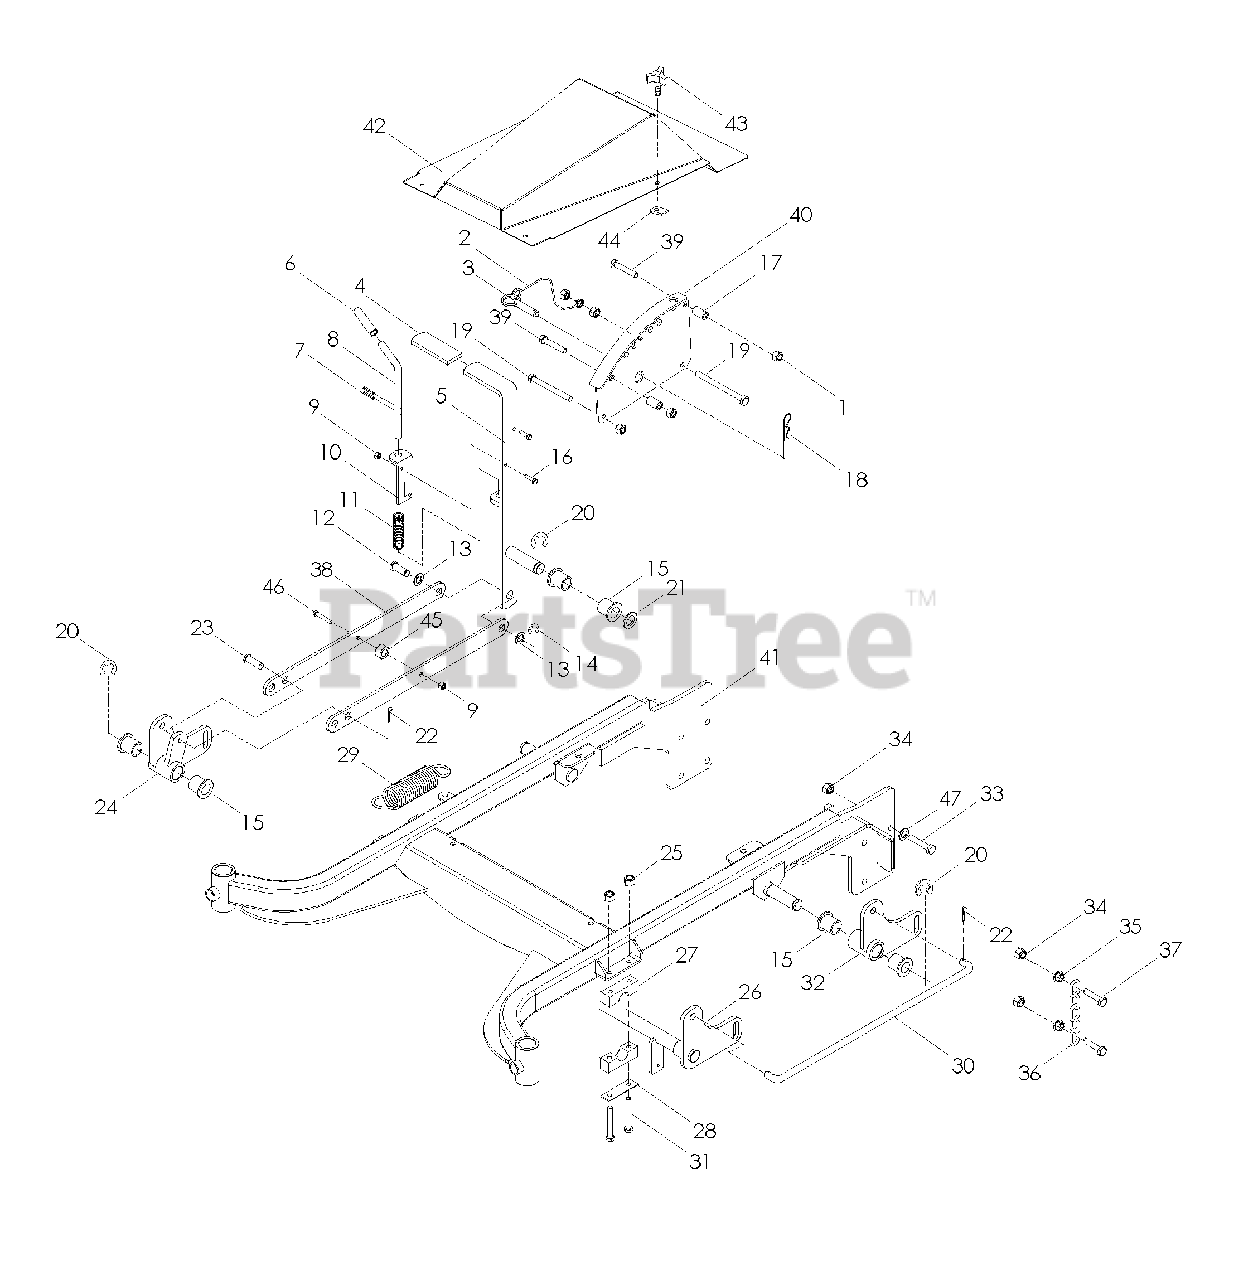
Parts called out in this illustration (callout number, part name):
1	NUT 3/8-16 HEX CNTRLK
4	GRIP, LIFT LEVER
5	LEVER, LIFT
7	PIN, GROOVED
8	PIN, LIFT LEVER
9	NUT 1/4-20 CNTRLK
10	MOUNT, PIN
12	CLEVIS PIN
13	BUSHING 5/8 MACHINERY
14	E-RING 5/8
15	BUSHING 7/8 FLANGED
16	HCS 1/4-20 x 3/4
18	HAIRPIN 2 1/2
19	HCS 3/8-16 x 4 1/2
20	E-RING 7/8
21	BUSHING, MACHINE
22	PIN, COTTER 5/32 x 1 1/4
23	PIN, CLEVIS 3/8 x 1 1/8
24	BELLCRANK, RIGHT
25	NUT 5/16-18 HEX CTRLK
26	LIFT ARM, FRONT
27	BLOCK, PILLOW
28	PLATE, REINFORCEMENT
30	LINK, DECK LIFT
31	HCS 5/16-18 x 2 1/2
32	BELLCRANK, LEFT
33	HCS 7/16-14 x 1
34	NUT 7/16-14 CNTRLK
35	NUT 7/16-14 WHIZ
36	CHAIN, LIFT
37	HCS 7/16-14 x 1 1/2
38	LINKAGE, FLAT
39	HCS 3/8-16 x 2
40	PLATE, HEIGHT ADJUST
43	KNOB
46	HCS 1/4-20 x 1 1/4
47	WASHER 3/8 FLAT
